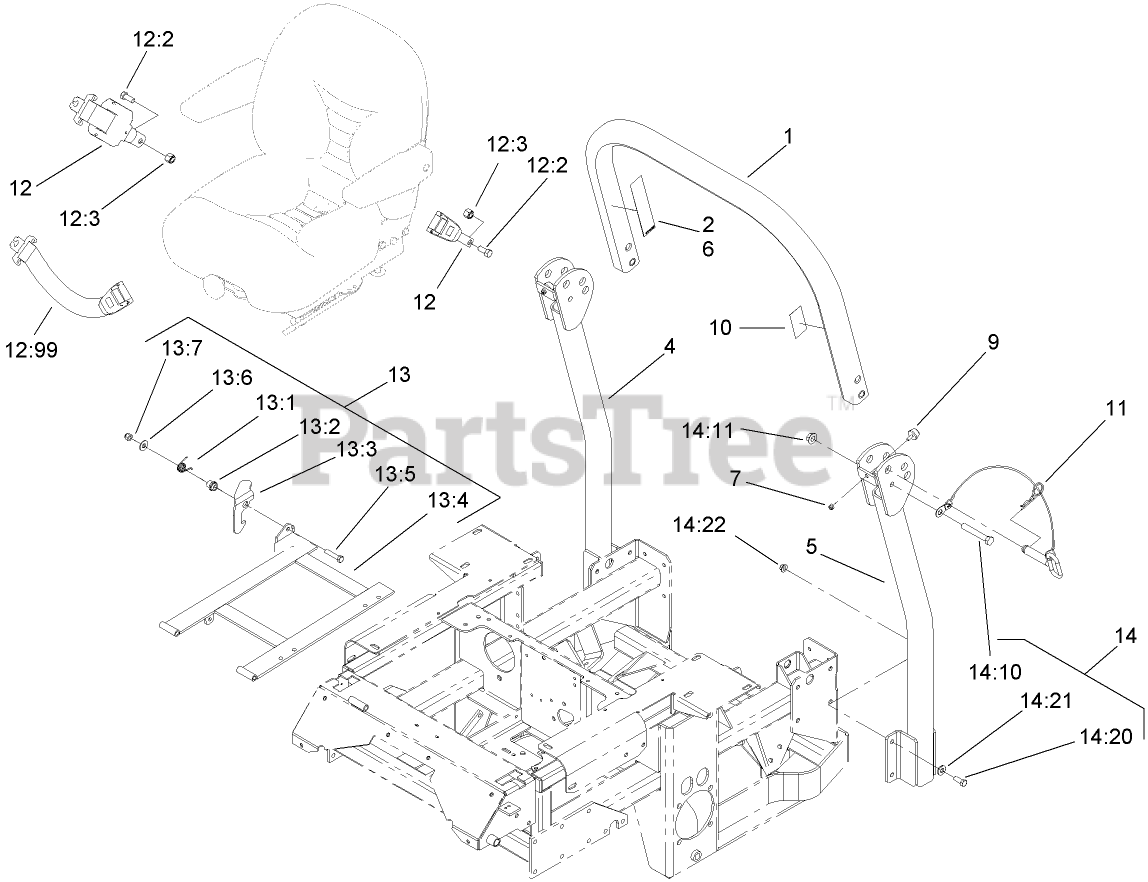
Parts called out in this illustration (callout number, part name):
1	Upper Tube ASM
2	DECAL-WARNING, FOLDING ROPS
4	TUBE-SUPPORT, RH
5	TUBE-SUPPORT, LH
6	DECAL-WARNING
7	NUT-LOCK, NI
9	BUMPER-RUBBER
10	DECAL-ROPS
11	PIN-FOLD, ROPS
12	RETRACTABLE SEATBELT KIT
12:2	SCREW-HH
12:3	NUT-LOCK
12:99	SEAT BELT EXTENSION KIT
13	SEAT FRAME SINGLE LATCH ASM
13:1	CATCH-LATCH, SINGLE
13:2	SPRING-TORSION, LATCH
13:3	BUSHING-LATCH, SEAT
13:4	FRAME-SEAT, SINGLE LATCH
13:5	WASHER-FLAT
13:6	NUT-LOCK, NI
13:7	SCREW-HH
14	BAG-BOLT
14:10	SCREW-HH
14:11	NUT-HF
14:20	SCREW-HH
14:21	WASHER-BELLEVILLE
14:22	NUT-HHF, WHIZ
